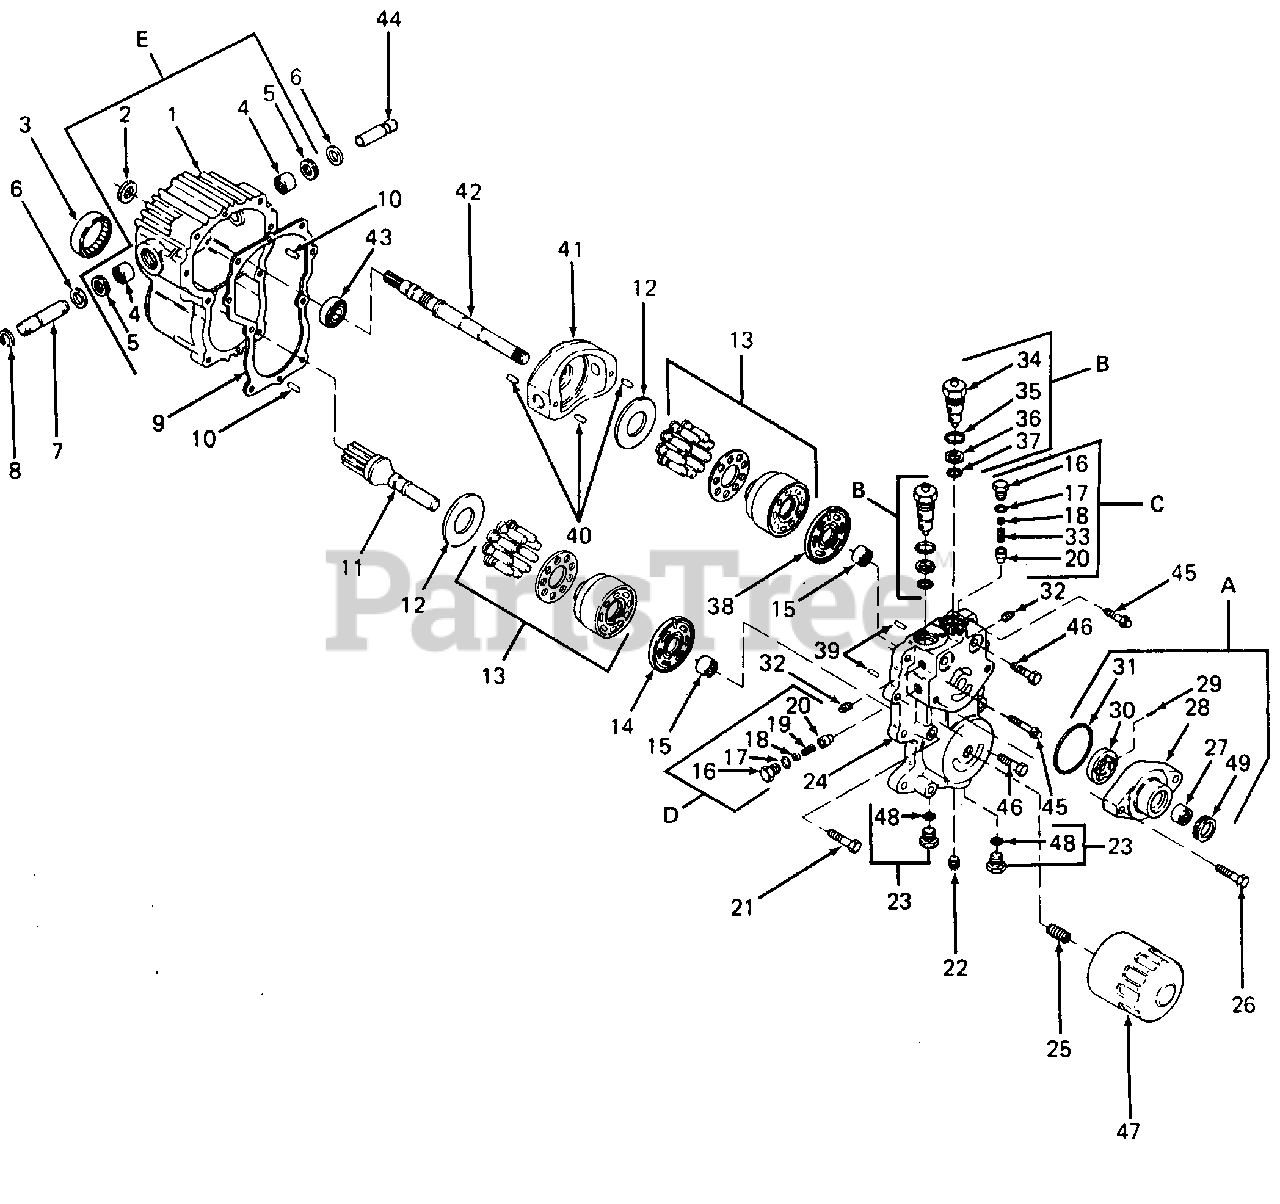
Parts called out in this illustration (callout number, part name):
1	Housing, Transmission
2	Seal, Lip
3	Bearing, Roller
4	Bearing, Needle
5	Seal, Lip
7	Shaft, Trunnion
8	Ring, Retaining
9	Gasket
10	Pin
11	Shaft, Motor
12	Plate, Thrust
13	Block, Cylinder
14	Plate, Valve
15	Bearing, Roller
16	Plug
17	O-Ring
18	Kit, Shim Pack
19	Spring, Center Relief Valve
20	Cone, Relief Valve
24	Center Section
27	Bearing, Needle
28	Charge Pump Housing
30	Gerotor
33	Spring, Implement Relief
34	Valve
36	Ring, Back-up
38	Plate, Valve
42	Shaft, Pump
44	Shaft Assembly, Trunnion
45	Screw, 12 Point
47	Oil Filter
49	Seal, Lip
A	Kit, Charge Pump
B	Valve Assembly
C	Kit, Relief Valve
D	Kit, Relief Valve
E	Housing Assembly
